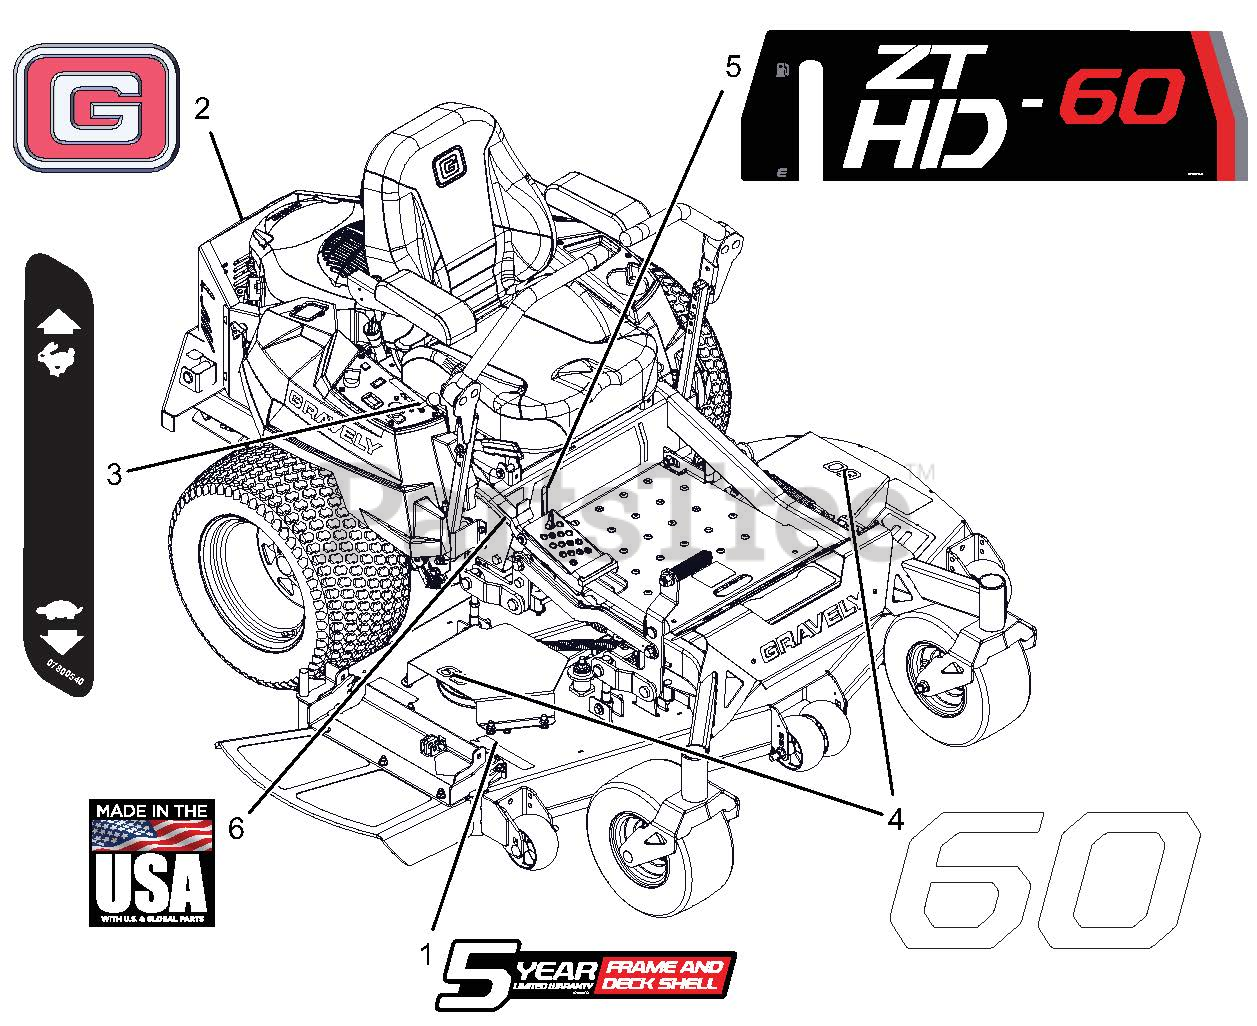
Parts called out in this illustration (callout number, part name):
1	DECAL, DECK 5 YEAR-GRAVELY
2	DECAL, GRAVELY BRAND
3	DECAL, DASH DECAL
4	DECAL, 60"
5	DECAL - 52HD
6	DECAL, MADE IN USA
